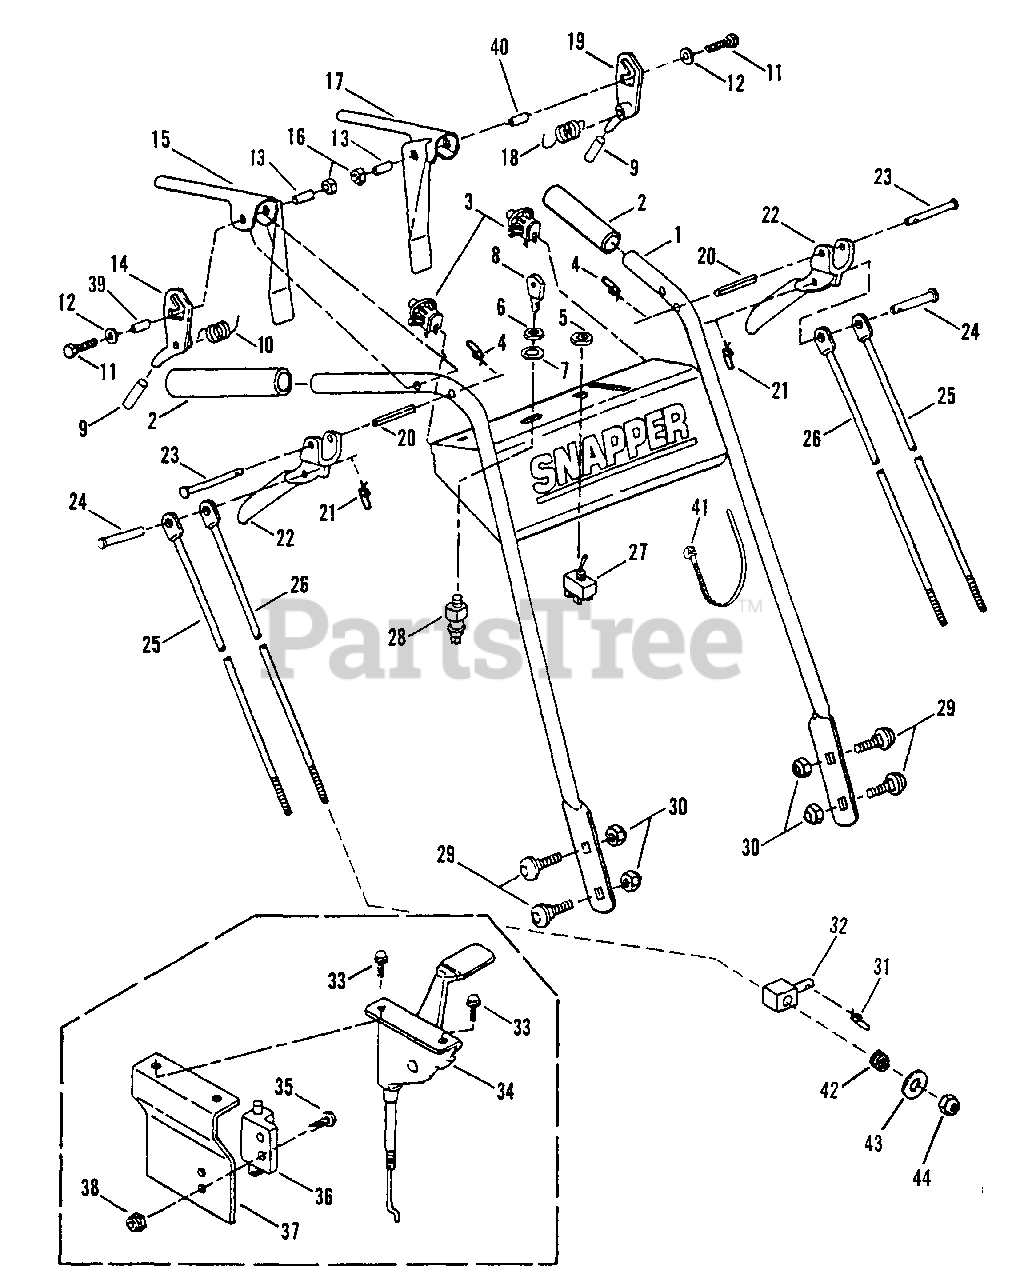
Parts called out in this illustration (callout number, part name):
1	ASSEMBLY, Handle, Pistol Grip
2	GRIP, Handle Assembly
3	SWITCH, OPC
4	PIN, 5/16 Self-locking Cotter
5	NUT, 1/2-27 Hex (Special)
6	NUT, 5/8-32 Hex (Special)
7	WASHER, 5/8 Internal Tooth Lock
8	KEY (With Cover)
9	GRIP, Latch
10	SPRING, Torsion (Left Hand)
11	BOLT, 1/4-20 X 3", GD5
12	WASHER, 1/4 Flat
13	SPACER, OPC
14	LATCH Weldment, (Right Hand)
15	GRIP, Pistol, OPC (Right Hand)
16	NUT, 1/4-20 Hex Top Lock, Grade B
17	GRIP, Pistol, OPC (Left Hand)
18	SPRING, Torsion (Right Hand)
19	LATCH Weldment, (Left Hand)
20	PIN, 5/16 x 1-1/8" Roll
21	PIN, 1/2" Self-locking Cotter
22	LEVER, Drive (With Grip)
23	PIN, 3/16 x 1-3/4" Clevis
24	PIN, 5/16 x 2" Clevis
25	ROD, Traction
26	ROD, Traction Brake
27	SWITCH
28	SWITCH, ON-OFF
29	BOLT, 3/8-16 x 1" Short Neck Carriage, Grade 2
30	NUT, 3/8-16 HEX NYLON LOCK
31	COTTER-PIN, 1/2" Self-Locking
32	SWIVEL
33	SCREW, #10-24 x 1/2" Hex Washer Self-Tap (Torx)
34	CONTROL, Throttle
35	SCREW, #10-24 x 1/2" Hex Head, Machine
36	SWITCH, OPC
37	BRACKET, Reverse Throttle
38	NUT, #10-24 Hex Nyloc
39	SPACER, Brake (outer)
40	SPACER, Brake (inner)
41	CABLE TIE, 7"
42	SPRING, Friction Pack
43	WASHER, 3/8" USS
44	NUT, 3/8-16 HEX NYLON LOCK
